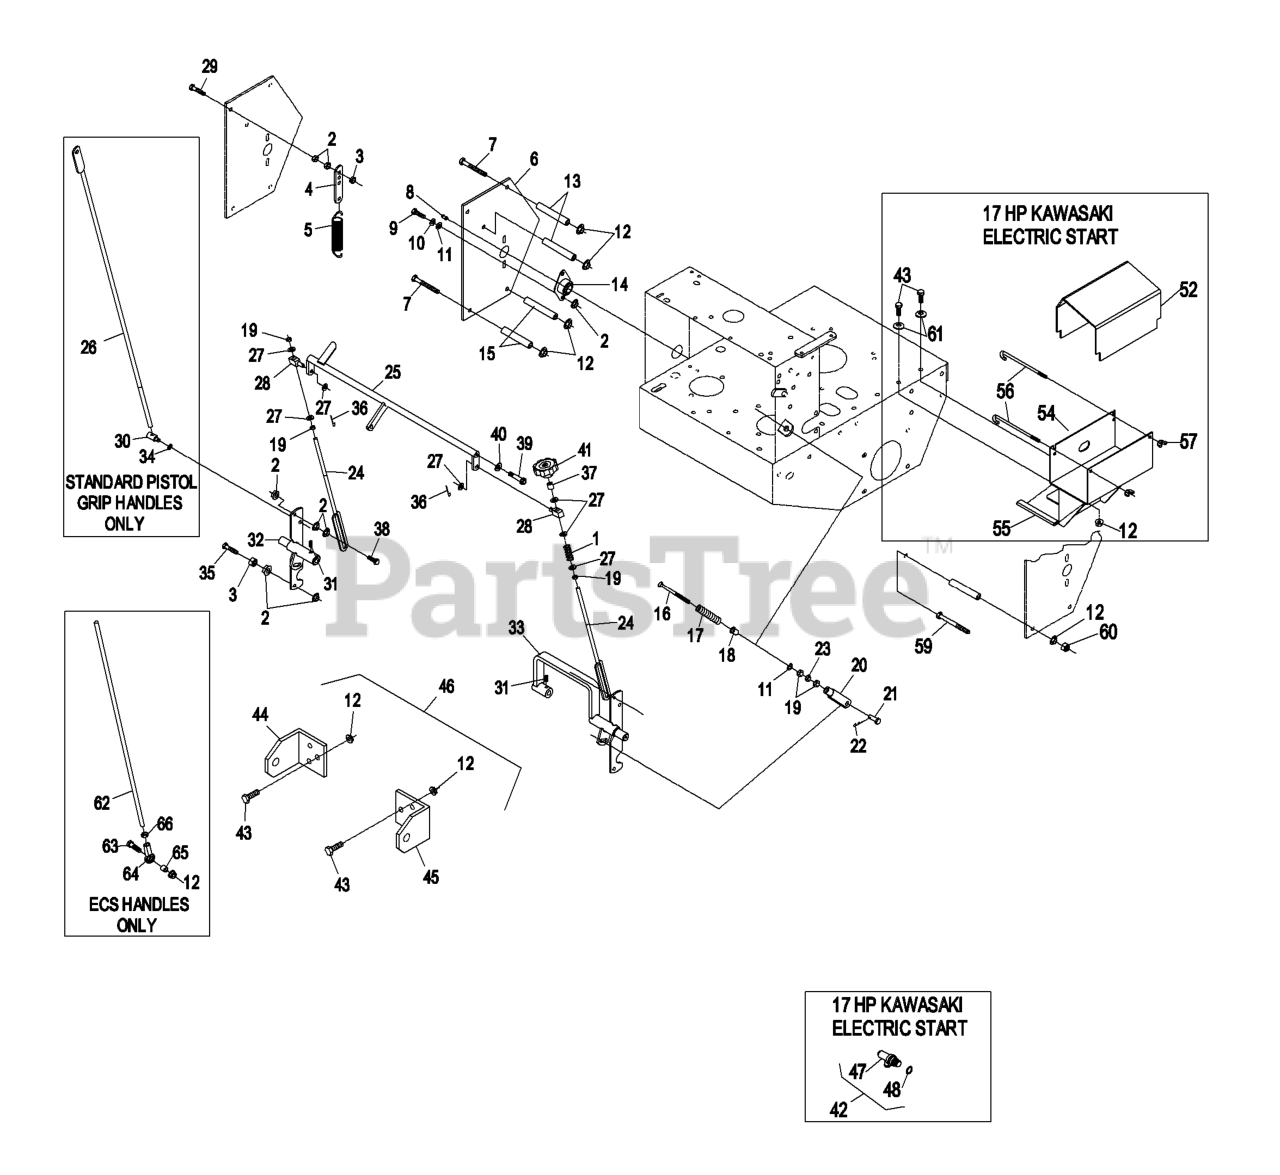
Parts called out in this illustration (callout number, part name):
1	SPRING-COMPRESSION
3	NUT-LOCK, NI
4	TAB-SPRING, EXTENSION
5	SPRING-EXTENSION
7	SCREW-HH
8	FITTING-GREASE
9	SCREW-HH
10	WASHER-LOCK
11	WASHER-FLAT
12	NUT-HHF, WHIZ
13	SPACER-SHIELD
14	BEARING-FLANGE, SIDE
15	SPACER-SHIELD
16	BOLT-RETURN, NEUTRAL
17	SPRING-RETURN, NEUTRAL
18	BUSHING-FLANGED
19	NUT-HEX
20	YOKE-ADJUSTABLE
21	PIN-CLEVIS
22	PIN-COTTER
23	NUT-JAM
24	LINK-CONTROL, SPEED
26	ROD-LEVER, DRIVE
27	WASHER-PLAIN
29	BOLT-TAP, HH
30	SWIVEL-LEVER, DRIVE
31	SCREW-SET
32	SHAFT-CONTROL, LH
34	RING-RETAINING
35	SCREW-HH
36	PIN-COTTER
38	SCREW-HH
39	SCREW-HSH
40	WASHER-FLAT
41	KNOB-TRACKING
42	KIT, OIL DRAIN VALVE
43	SCREW-HH
45	BRACKET,SULKY RH
46	Sulky Kit
49	NUT-HF
50	INSULATOR, BATTERY -
51	CABLE-BATTERY, NEGATIVE
54	KIT,BATTERY STAND-TTHP ES
55	TRIM-LOK
56	BOLT - HOLD DOWN
57	WINGNUT
58	SCREW-HH
59	SCREW-HH
60	NUT-LOCK, NI
61	Washer, Disc Spring 3/8
62	LINK,DRIVE (PLTD)
63	SCREW-HH
64	JOINT-BALL END, LH
65	SPACER-TUBE, PUMP LINK
66	NUT-HEX JAM, LH
